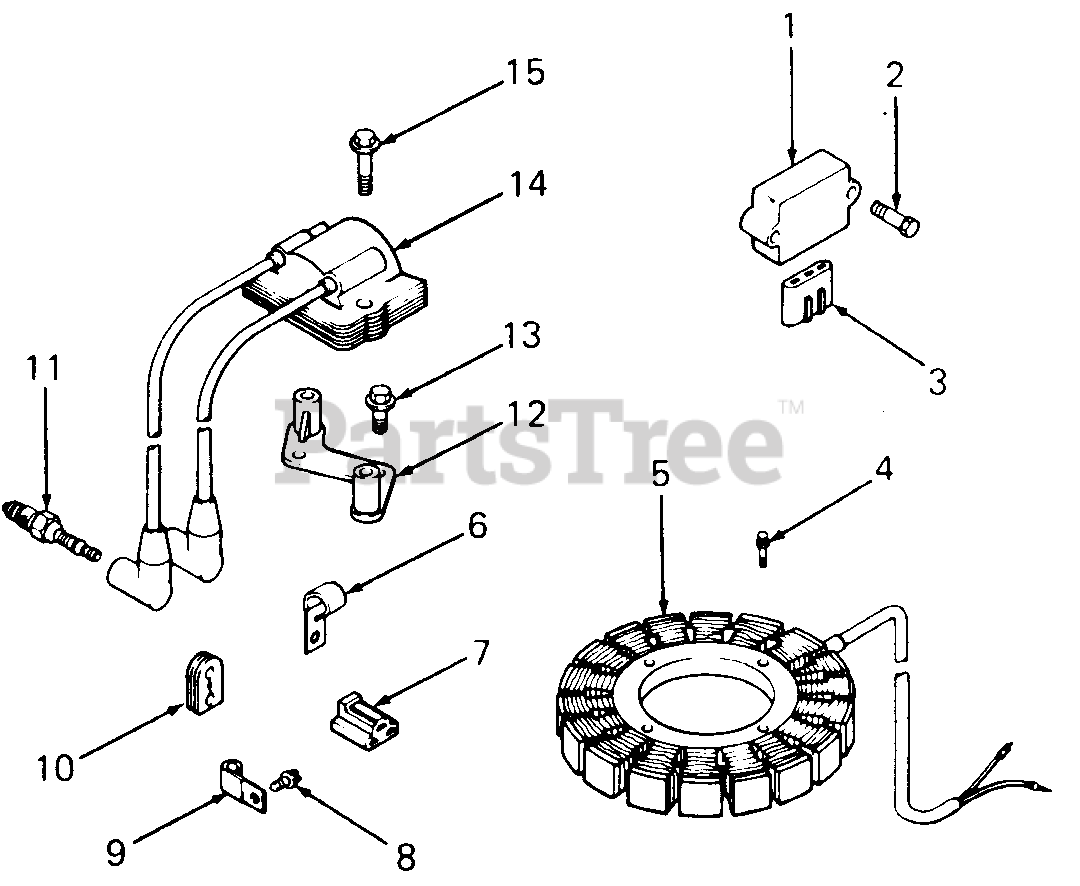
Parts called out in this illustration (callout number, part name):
1	Rectifier, Regulator
2	Screw, H.C. Sems, 1/4-20 X 5/8
3	Connector, Female (3 contact)
4	Screw, Hex Wash Hd, 10-24 X 3/4
5	Stator Kit, 15 amp
6	Clip, Cable
7	Connector, Male (3 contact)
8	Screw, Hex Wash Hd, 1/4-20 X 7/16
11	Spark Plug
12	Bracket, Module
13	Screw, Hex Wash Hd, 1/4-20 X 7/8
14	Module, Ignition w/ Diode
15	Screw, Hex Wash Hd, 1/4-20 X 1
